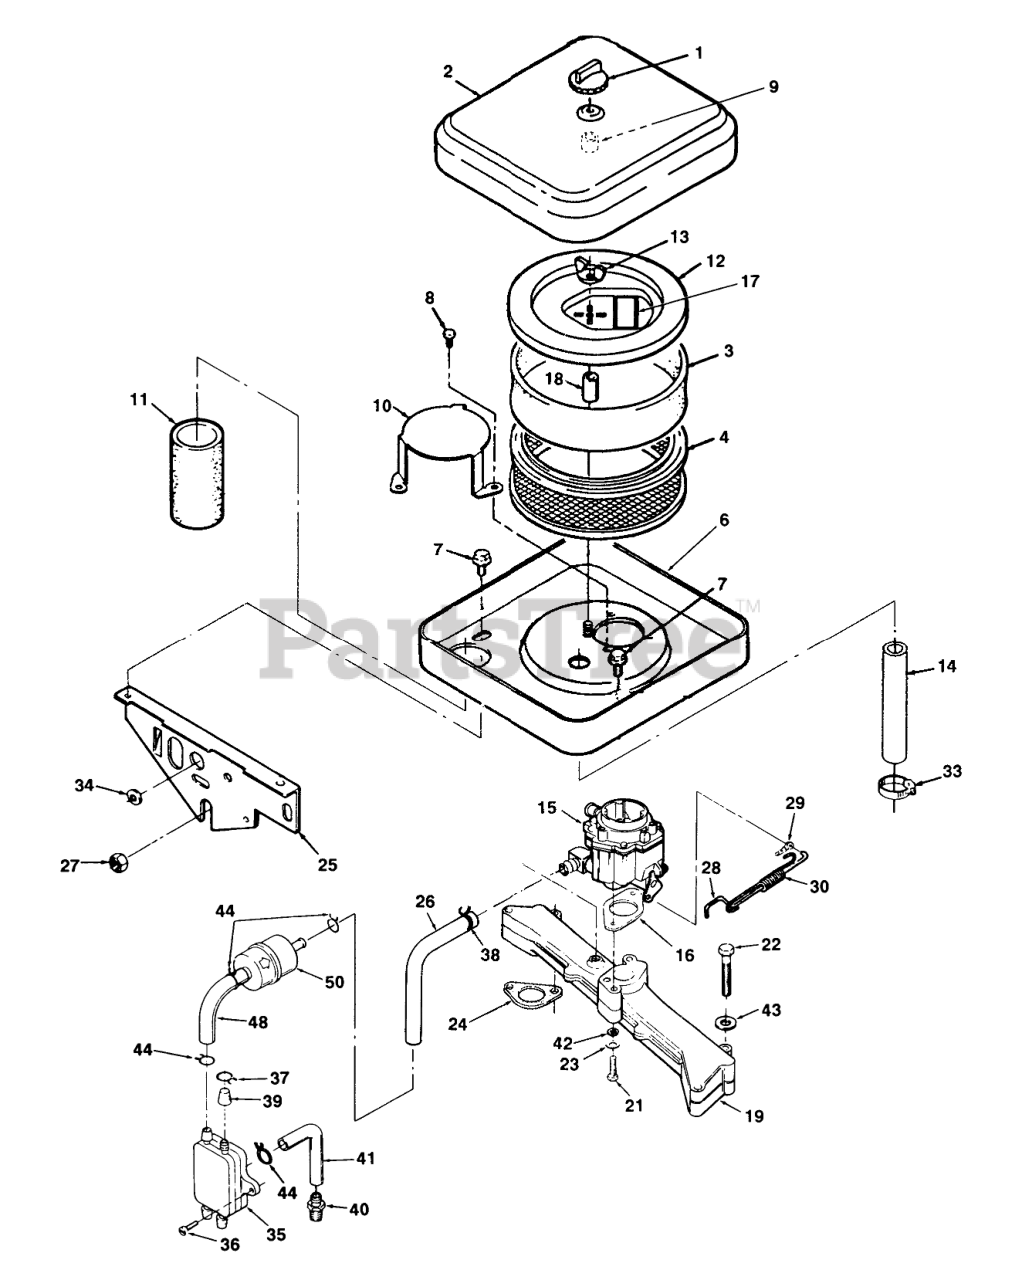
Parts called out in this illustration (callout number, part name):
1	Knob
2	COVER-AIR CLEANER
3	WRAPPER-AIR CLEANER ELEMENT
4	ELEMENT-AIR CLEANER
6	HOUSING-AIR CLEANER
7	Screw-Hex Washer Hd
8	Screw-HWH
9	SPACER-RUBBER
10	Air Deflector Plate
11	TUBE-AIR INTAKE
12	Cover-Element
13	1/4-20 WING NUT
14	HOSE-RUBBER, BREATHER
15	Carburetor
16	GASKET-CARBURETOR
17	DECAL-PERIODIC MAINTENANCE
18	SPACER-AIR CLEANER STUD
19	MANIFOLD - INTAKE
21	HEX HD CAP SCR
22	Screw-Hex Hd Cap
23	WASHER-FLAT
24	GASKET-MANIFOLD TO BLOCK
25	SUPPORT-AIR CLEANER
26	HOSE - FUEL
28	ROD-GOV CONTROL
30	Spring-Governor Rod
33	CLAMP-HOSE, BREATHER
34	GROMMET
35	Pump-Fuel (Incl. Hose Clamp & Fuel Cap)
37	CLAMP
39	CAP-FUEL OUTLET
40	CNCTR. - HOSE
41	HOSE-VACUUM
42	WASHER-FLAT
43	WASHER-FLAT
44	CLAMP-HOSE
50	FILTER-FUEL
